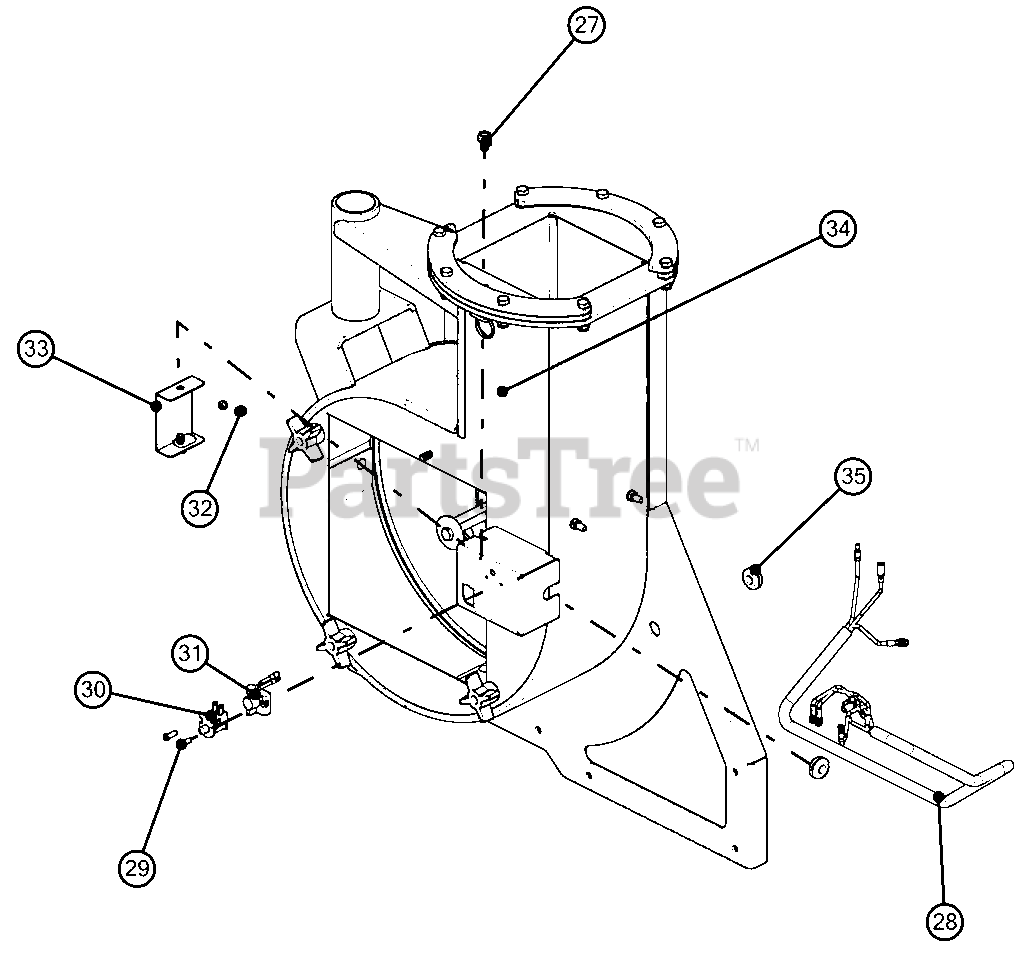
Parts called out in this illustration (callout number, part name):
27	BOLT, 5/16-18X .625 FGH 5
28	WIRE HARNESS, 14 HP TRUCK LOADER
29	SCR-MC 8-32 X .62 NICKEL
30	SWITCH-SNAP MTG NC REVO
31	STOP SWITCH
32	NUT-LK-NYL 8-32 W/INSRT YWZC
33	SLDT, SWITCH COVER
34	WLDT, BLOWER 14 TRUCK LOADER
35	GROMMET, ROUND RUBBER .625 X .19
